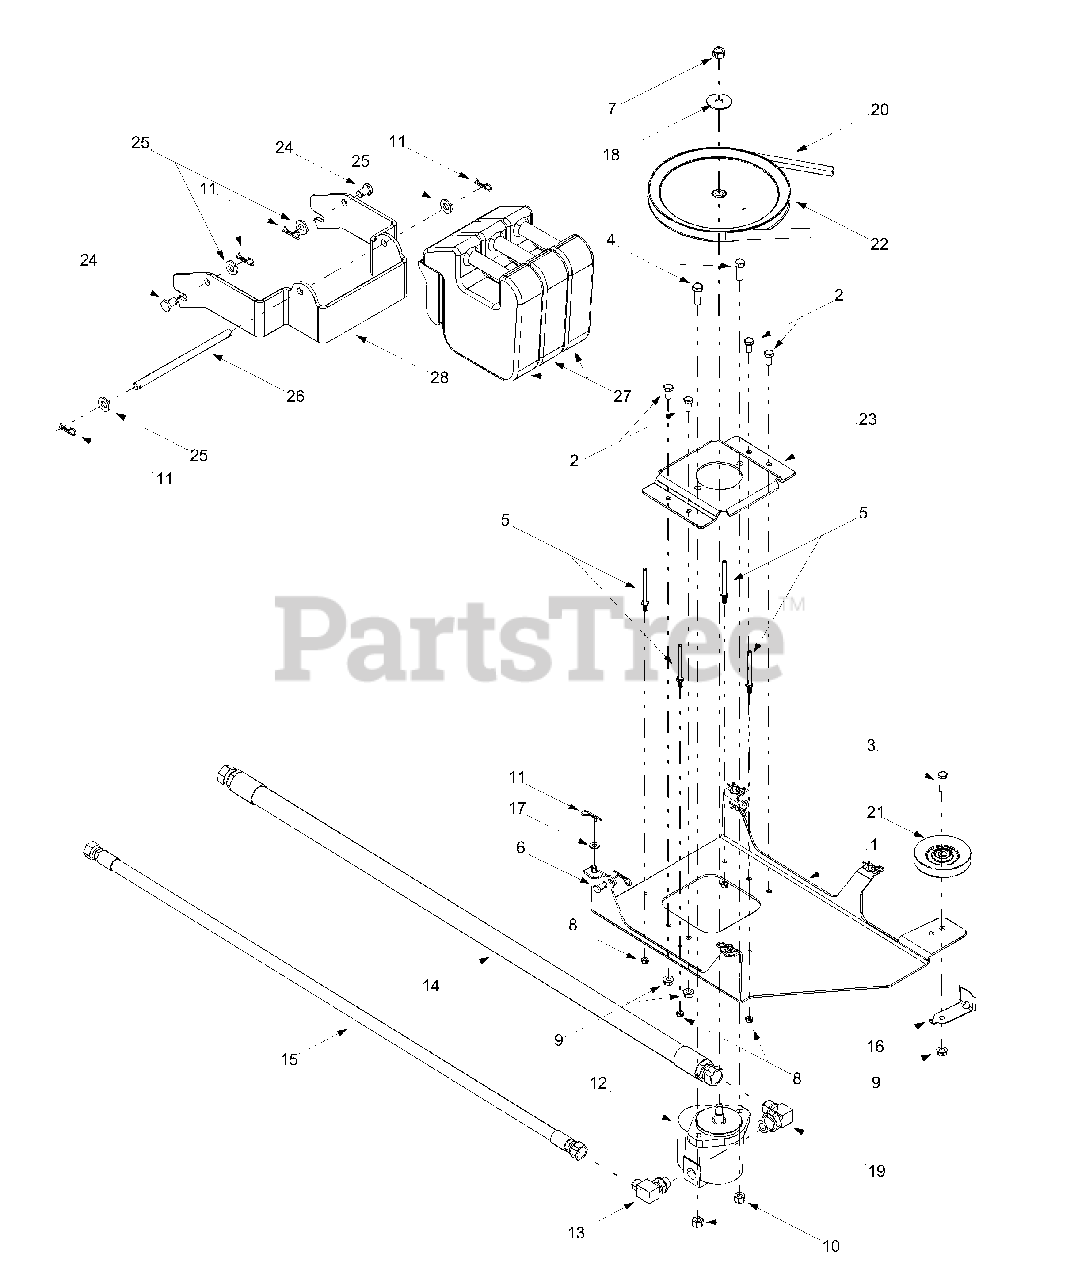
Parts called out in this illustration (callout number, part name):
1	Hydraulic Pump Bracket Ass'y
2	Hex Cap Screw, 3/8-16 x .75
3	Hex Cap Screw, 3/8-16 x 1.25
4	Hex Cap Screw, 7/16-20 x 1.25
5	Belt Keeper Pin
6	Clevis Pin, 3/8 x .75
7	Hex Lock Nut, 1/2-20
8	Hex Lock Nut, 1/4-20
9	Hex Lock Nut, 3/8-16
10	Hex Lock Nut, 7/16-20
11	Click Pin, .092 x 1.64
12	Eaton Hydraulic Pump
13	90° Hydraulic Adapter, 7/8
14	Hydraulic Hose, 1.0625-12 x 54
15	Hydraulic Hose, .875-14 x 49
16	Belt Guard
17	Flat Washer, .344 x .688 x .065
18	Flat Washer, .531 x 1.75 x .090
19	90° Hydraulic Adapter, 1-1/16
20	V-belt
21	Idler Pulley, 5/8 x 4.0
22	Drive Pulley, 10.0
23	Pump Mounting Bracket
24	Clevis Pin, .5 x .78
25	Flat Washer, .531 x 1.062 x.1 34
26	Weight Guard Rod
27	45 lb. Suitcase Weight
